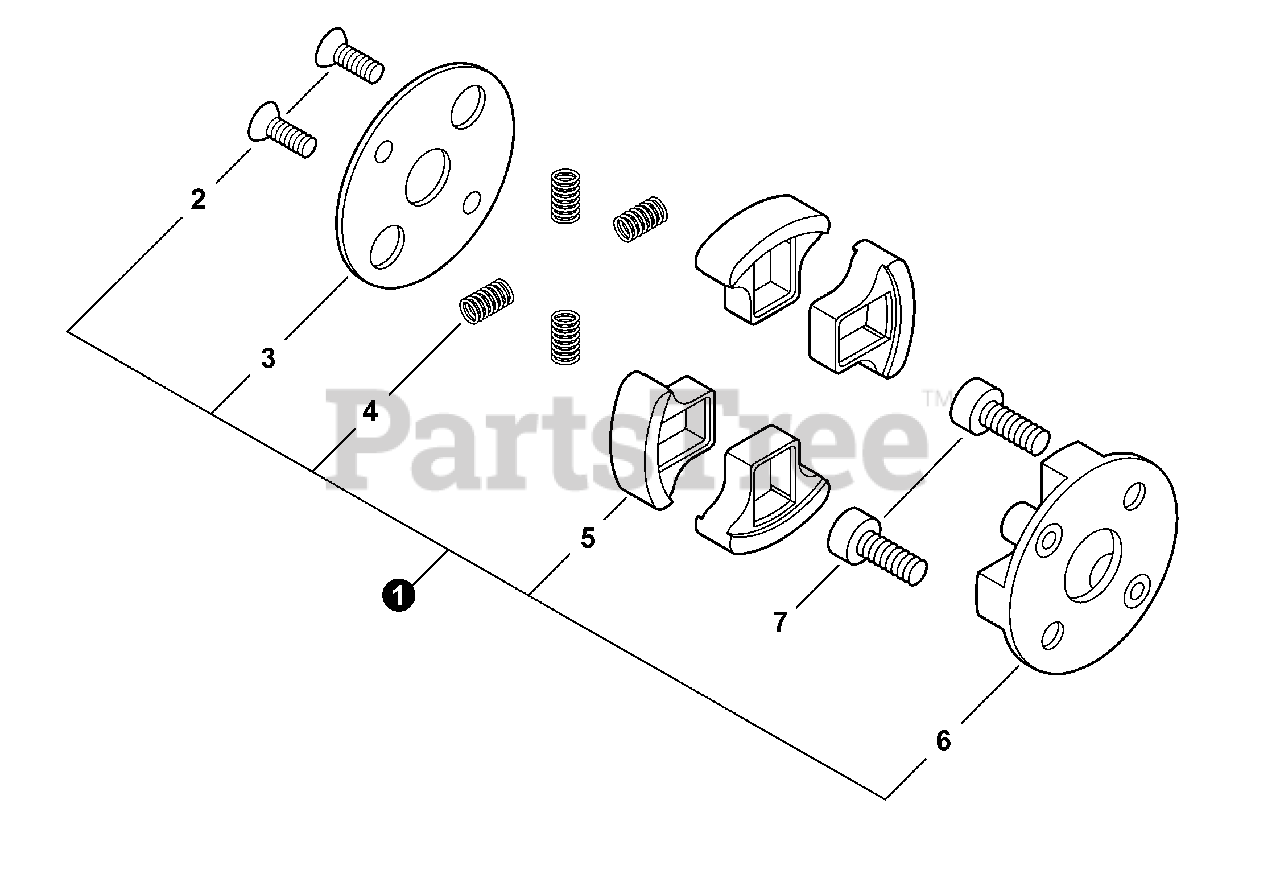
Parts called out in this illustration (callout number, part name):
1	CLUTCH ASSY
3	PLATE, CLUTCH
4	SPRING, CLUTCH
5	SHOE, CLUTCH
6	HUB, CLUTCH
7	BOLT, CLUTCH
